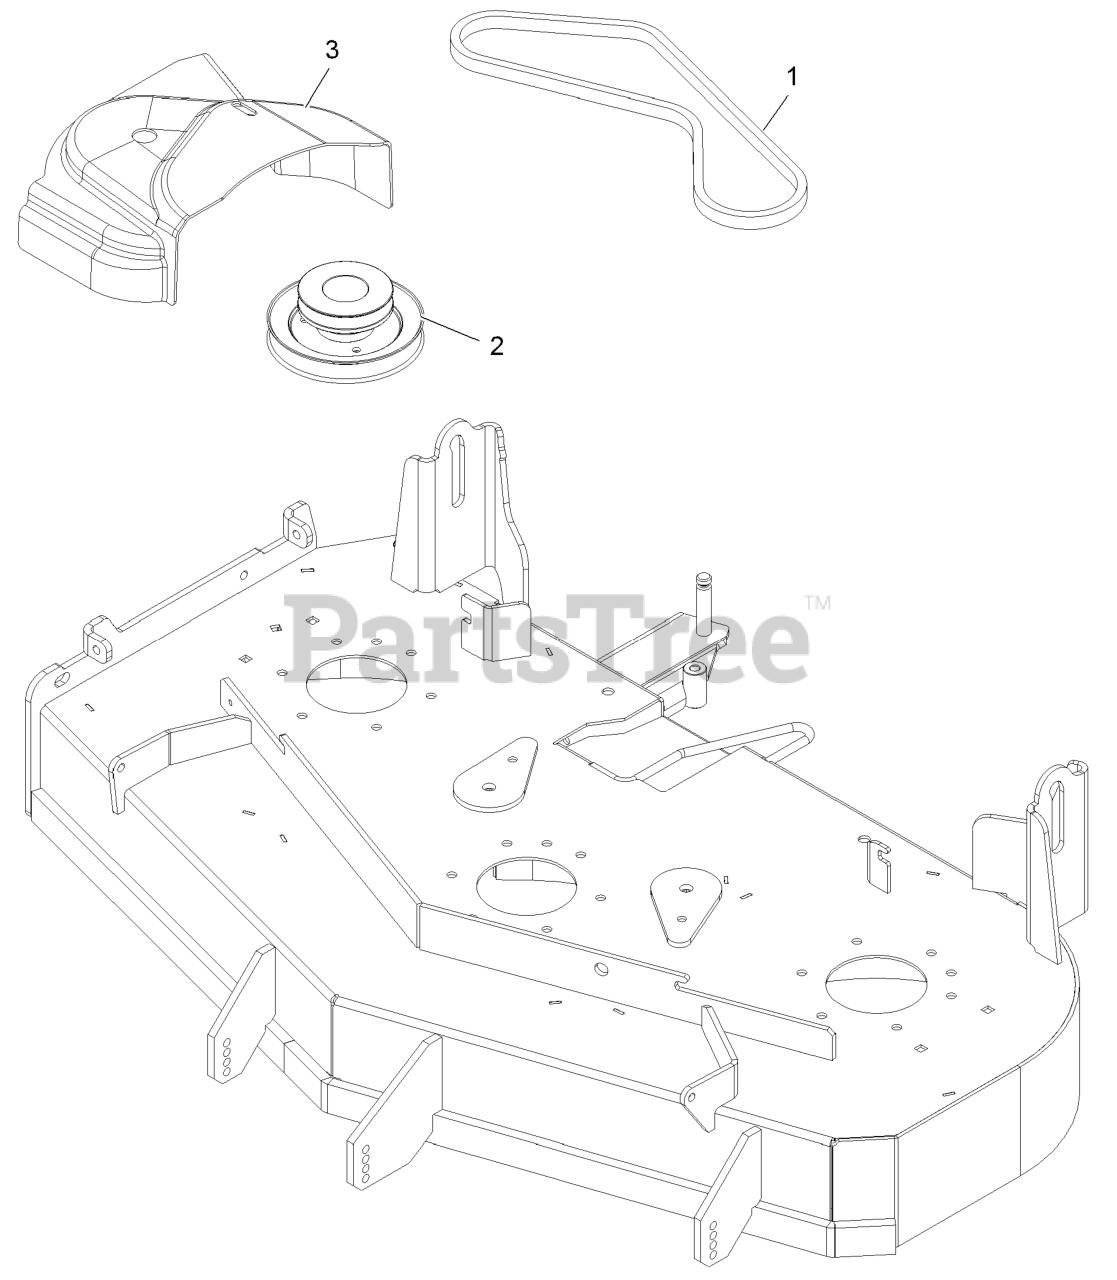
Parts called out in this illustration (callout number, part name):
1	BELT-BLOWER
2	JACKSHAFT-UV DRIVE, 484 S
3	COVER,BELT UV 48
